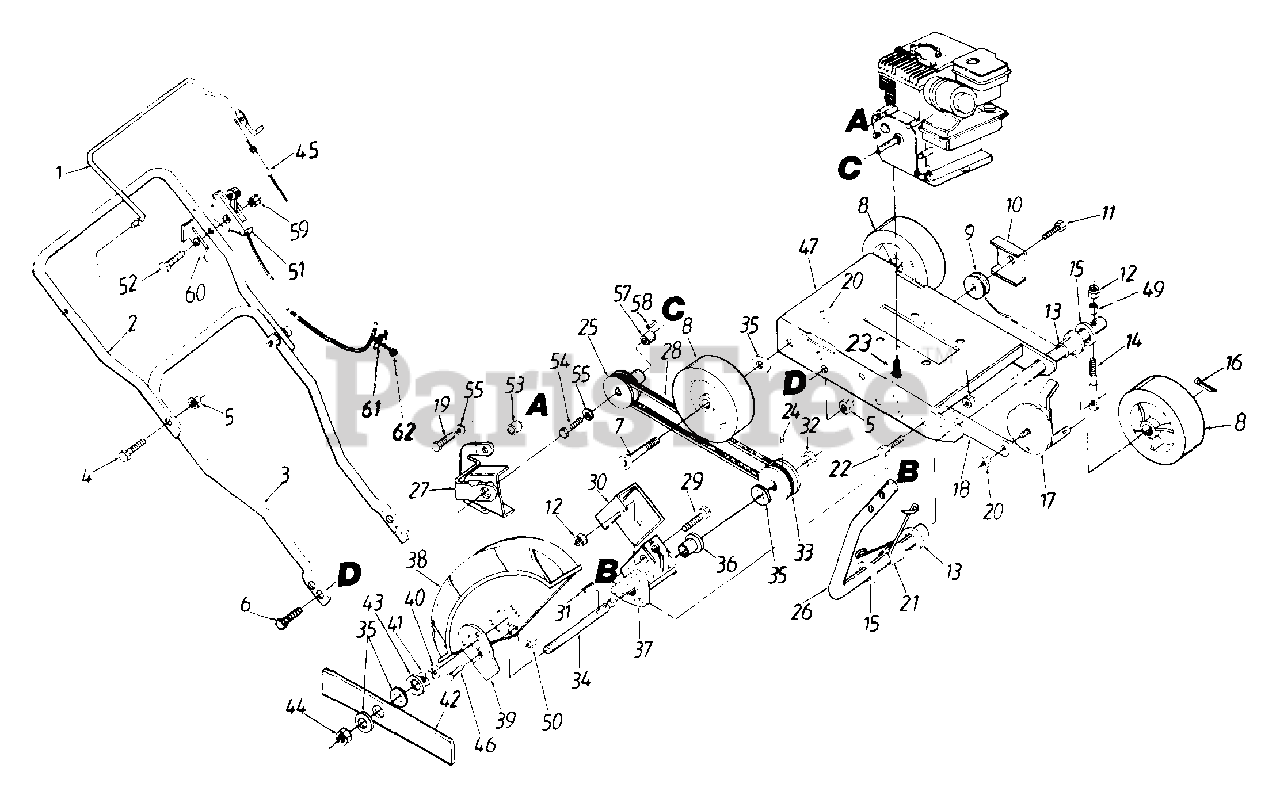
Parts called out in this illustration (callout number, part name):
1	Control Handle
2	Upper Handle
3	Lower Handle
4	Hex Bolt 5/16-18 x 1.5"
5	Hex L-Nut 5/16-18 Thd.
6	Hex Bolt 5/16-18 x .625"
7	Wheel Bolt
8	Wheel - 6"
9	Idler Pulley
10	Bracket - Idler Pulley
11	Bolt(Special)
12	Hex L-Nut 5/16-18 Thd.
13	Bushing
14	Arm-Pivot Rod
15	Flat Washer 5/8" I.D.
16	Cotter Pin 1/8 x 3/4"
17	Adjuster Assembly (Depth)
18	Arm - Front Wheel
19	Hex Bolt 5/16-24 x 1" (Gr. 5)
20	Hex Keps L-Nut 3/8-16 Thd.
21	Spring - Cutterhead
22	Hex Bolt 5/16-18 x 1" Lg.
23	Engine Bolt (Special)
24	Locking Set Scr. 5/16-18
25	Engine Pulley
26	Rod - Cutterhead
29	Hex Bolt 5/16-18 x 1.5"
30	Belt Guard (Cutterhead)
31	Woodruff Key
32	Retaining Ring
33	Pulley - Cutterhead
34	Shaft - Cutterhead
35	Bell-Wash. 3/8" I.D.
36	Bushing - Cutterhead
37	Housing - Cutterhead Shaft
38	Blade Guard
39	Edge Guide
40	Flat Washer .035 Thk.
41	Heavy Hex Jam Nut 3/8-24
42	9" Replacement Blade
43	Fl-Wash. 3/8" I.D.
44	Hex Nut 3/8-24 Thd.
45	Cable - Depth Control
46	Hex Self-Tap Scr. #10-24
47	Base - Edger Frame
49	Spacer - Pivot Arm
50	Nylok Nut #10-24
51	Throttle Control
52	Hex Bolt 1/4-20 x 1.75" Lg.
53	Spacer
54	Hex Bolt 3/8-24 x 1.75"
55	L-Wash 5/16" I.D.
57	Spacer
58	Sq. Key 3/16" x 1.5"
59	Hex L-Nut 1/4-20 Thd.
60	Stop Bracket
61	Cable Clamp
62	Hex Tap Scr. #8 x 3/8"
